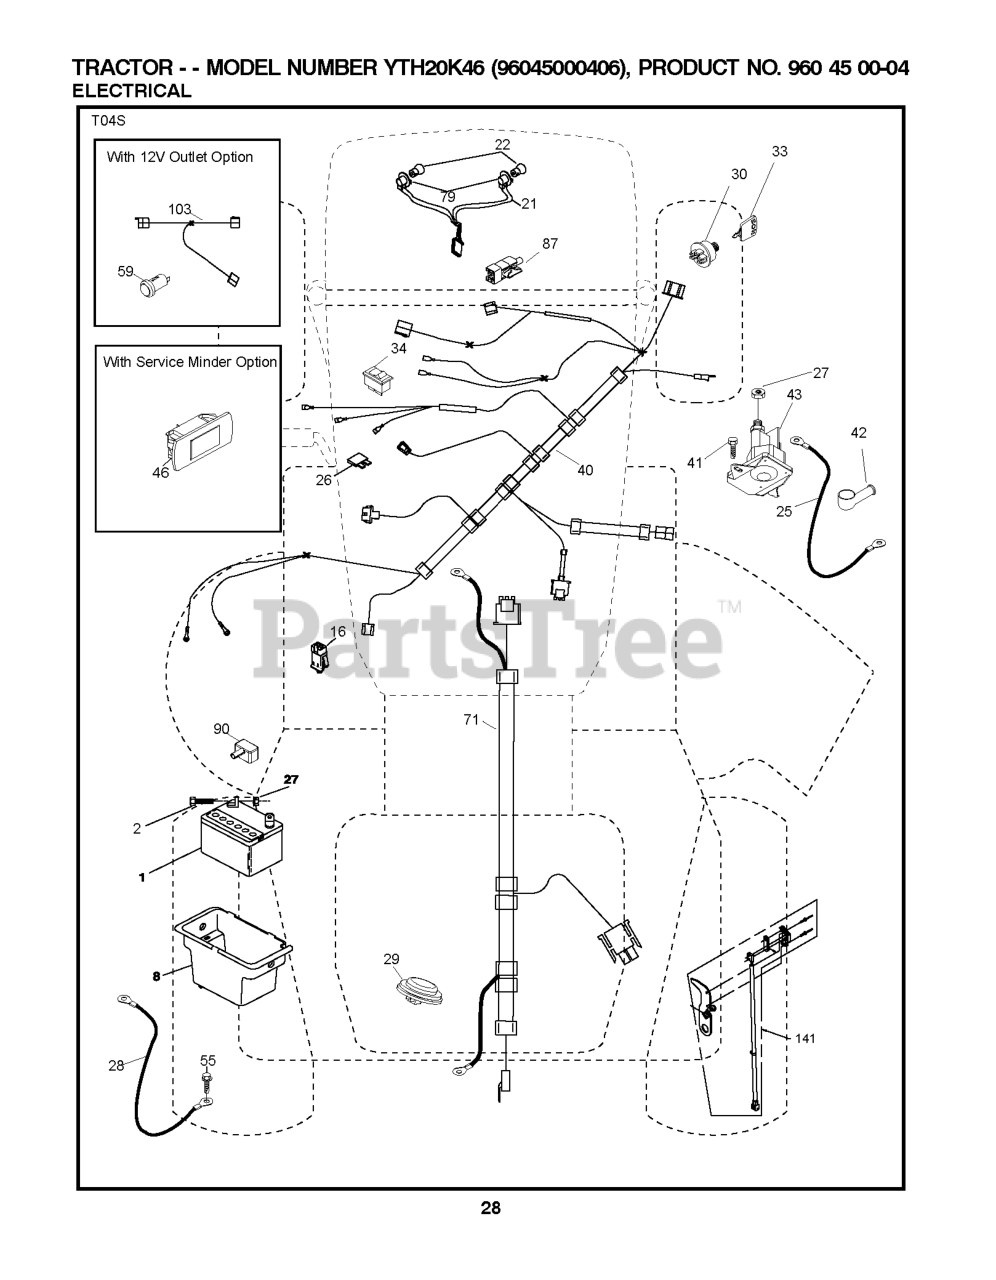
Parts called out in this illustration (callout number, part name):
1	Battery 12 Volt 25 Amp
2	BOLT.HEX.1/4.X.3/4.DICHROMATE
8	BOX.BATTERY.MNT.REAR.L
16	SWITCH INTERLOOK PUSH-IN
21	HARNESS ASSY LIGHT
25	CABLE.STARTER.6G.BL/RED.17.5
26	FUSE 20AMP
27	NUT
28	CABLE.BLACK.18"REAR.BA
29	SWITCH.SEAT.DELTA.OPC.
30	SWITCH.IGN.DELTA.W.LGH.ROS
33	KEY.CHAIN.BLISTER.PACK.GEN.USA
40	HARNESS IGN. DASH
41	SCREW
42	TERMINAL COVER
43	SOLENOID.W/BRASS.PLUNGER
46	RP.GUAGE.SRVCMNDR.HRMTR.
55	SCREW 5/16"
71	HARNESS.IGN.CHASS.TEX.REAR.BAT
79	BULB HOLDER ASM.
87	SWITCH.INTRLCK.CLUTCH.
90	COVER, TERMINAL BATTERY
141	KIT T2.ROS 71677
